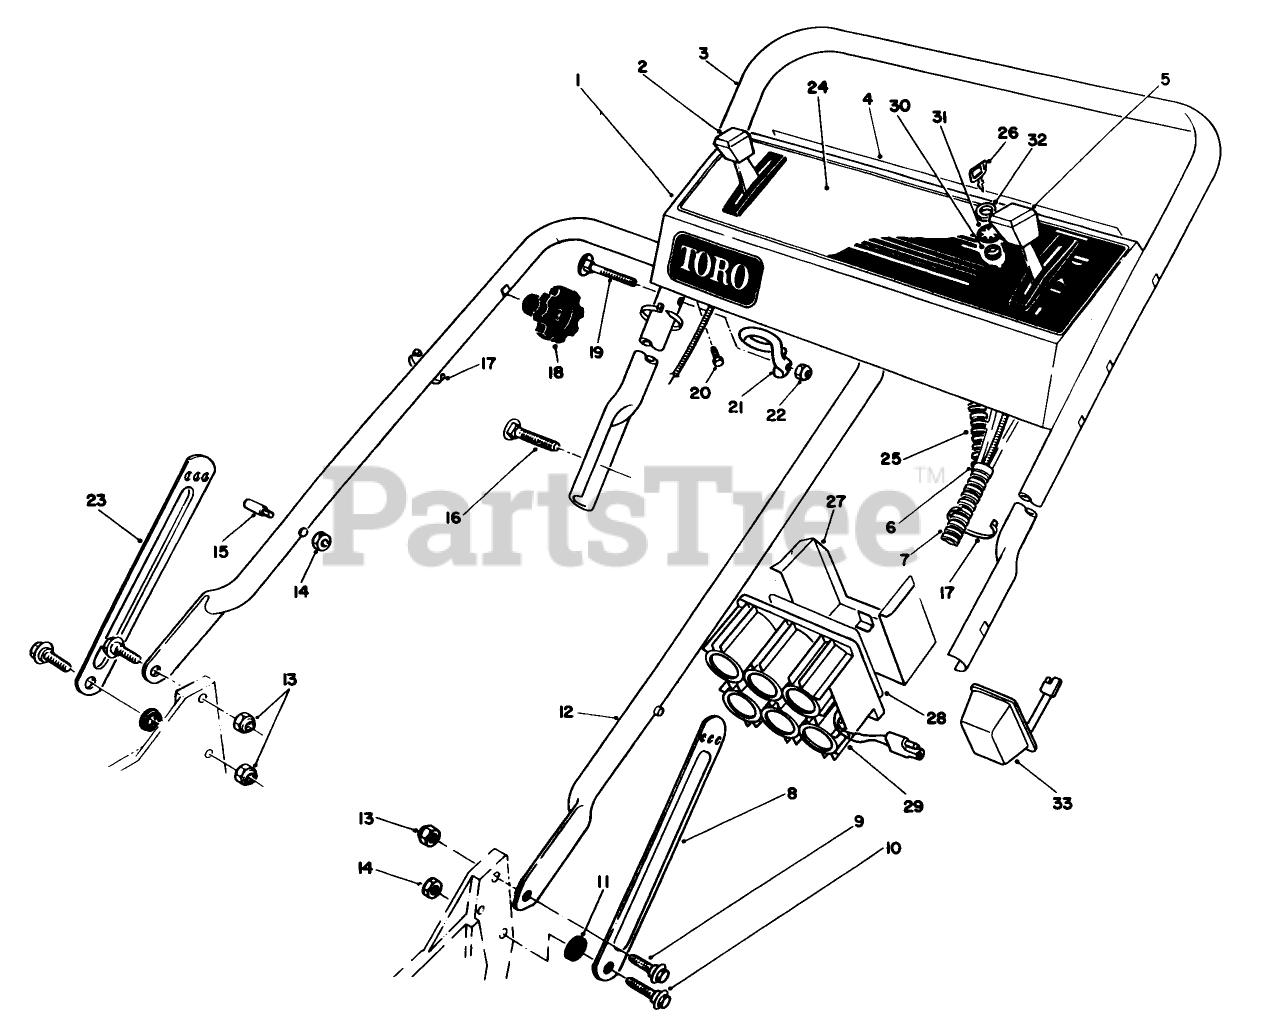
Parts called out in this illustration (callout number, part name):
4	DECAL-PANEL, DANGER
5	THROTTLE CONTROL
6	FITTING-RING
8	LH HANDLE LATCH
9	SCREW-SHOULDER
10	SCREW-SHOULDER
11	SPACER
13	NUT-LOCK, NI
14	NUT-LOCK, NI
15	HANDLE PIN
17	TIE-CABLE
19	HANDLE SCREW
20	SCREW-HWHTF
22	NUT-LOCK, NI
25	WIRING HARNESS
26	KEY-IGNITION
29	BATTERY ASSEMBLY,WET
30	STARTER SWITCH ASM
31	WASHER-LOCK
32	NUT-HH
